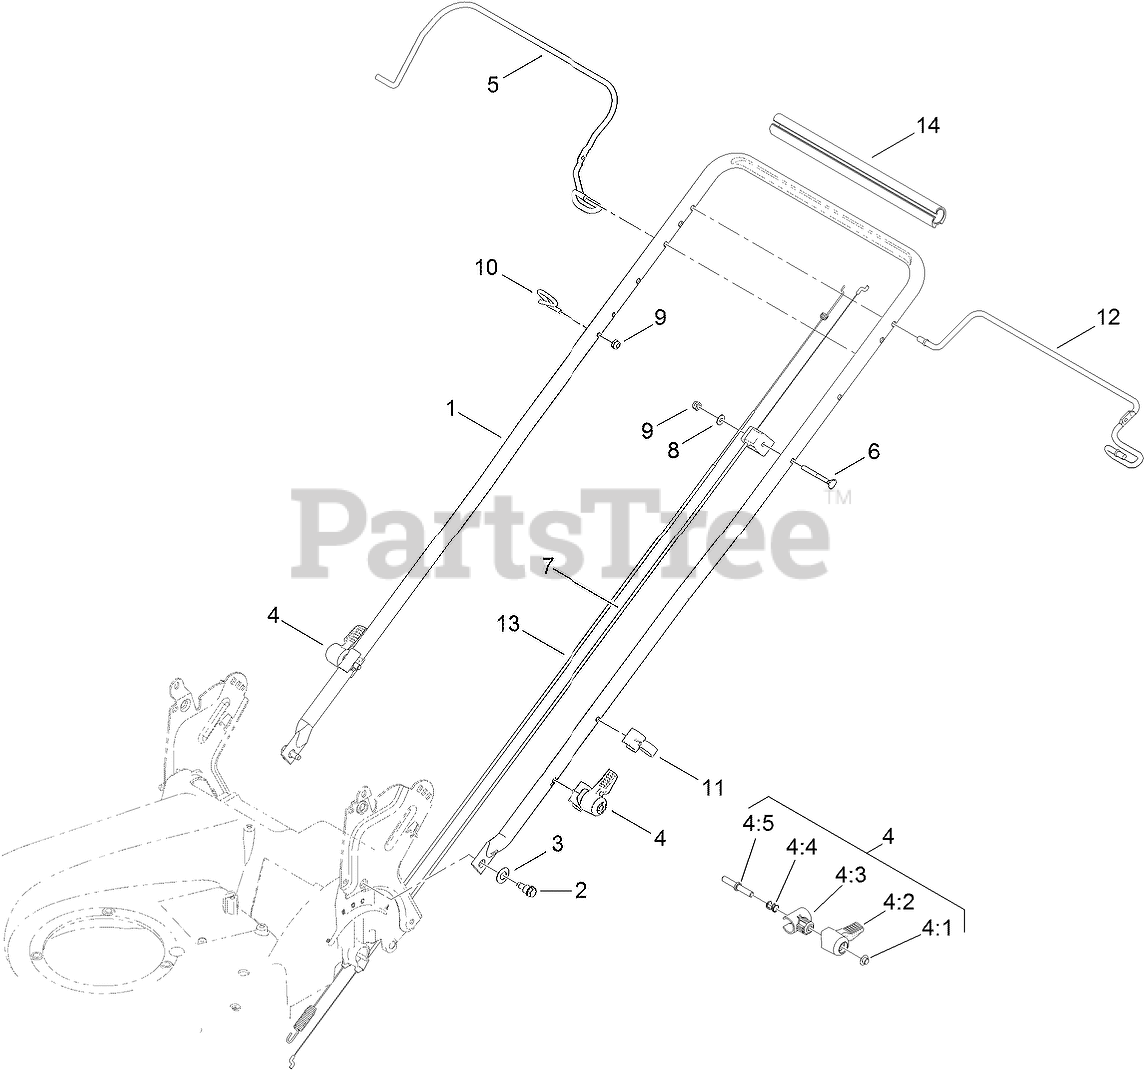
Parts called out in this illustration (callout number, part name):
2	BOLT-SHOULDER
3	WASHER-SPRING, CONICAL
4	QUICK RELEASE ASM
4:1	NUT-PUSH
4:2	LEVER
4:3	ANCHOR-SPRING
4:4	SPRING-COMPRESSION
4:5	ROD-RELEASE
5	BAIL-BRAKE
6	SCREW-HANDLE
7	CABLE-BRAKE
8	WASHER-FLAT
9	NUT-LOCK, NI
10	GUIDE-ROPE
11	GUIDE-CABLE
12	BAIL-TRACTION
13	CABLE-TRACTION
14	GRIP-HANDLE, COMFORT
